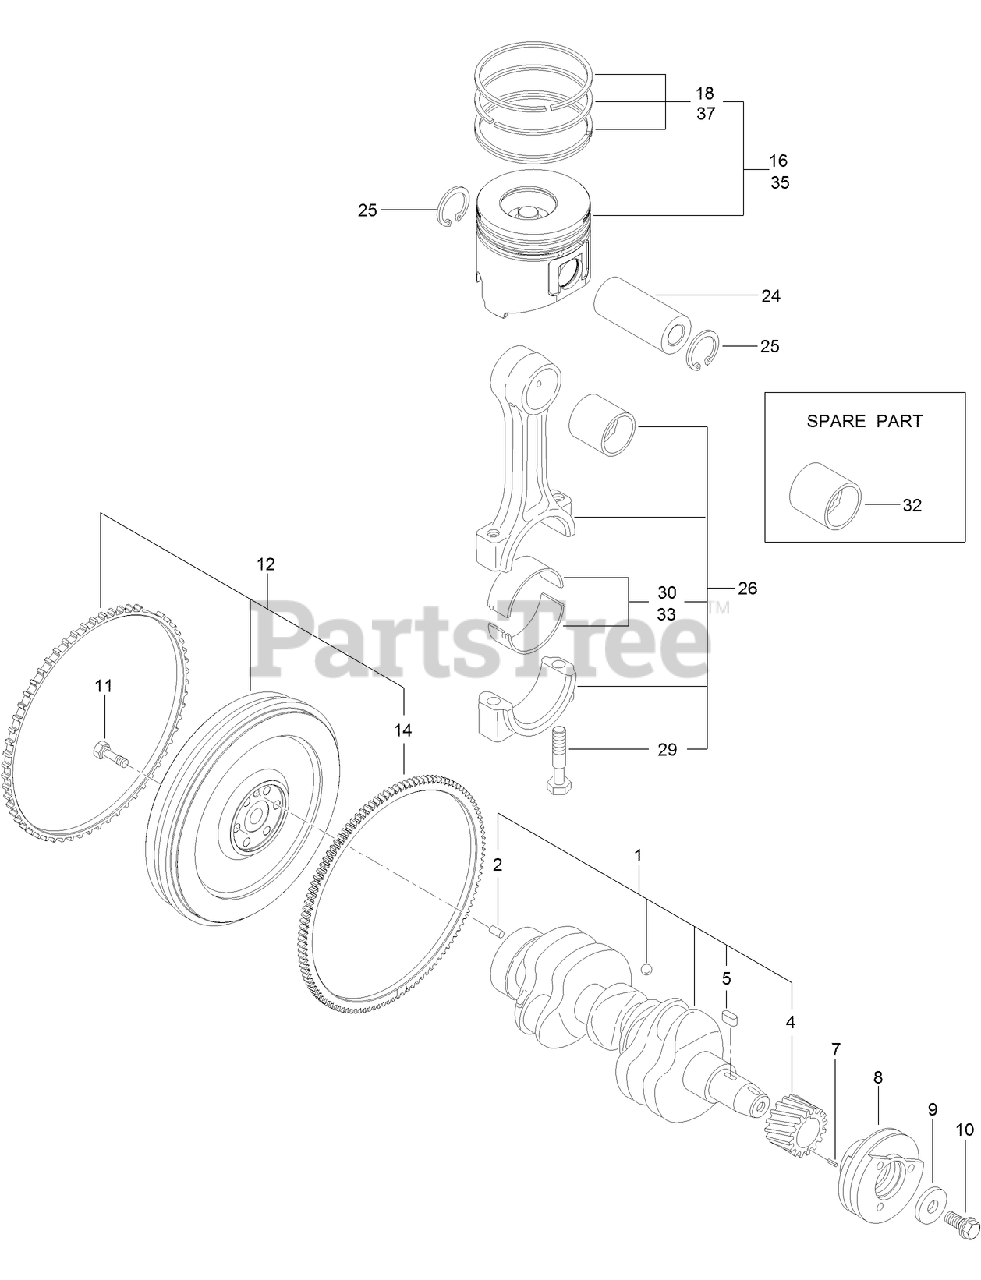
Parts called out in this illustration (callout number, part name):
1	CRANKSHAFT ASM
7	PIN-SPRING
8	PULLEY-V
9	WASHER
12	FLYWHEEL ASM
16	PISTON ASM
18	PISTON RING ASM
26	CONNECTING ROD ASM
30	PIN-CRANK
32	PIN-PISTON
33	PIN-CRANK (.25)
35	PISTON ASM (0.25 O S)
37	RING SET (0.25 O S)
